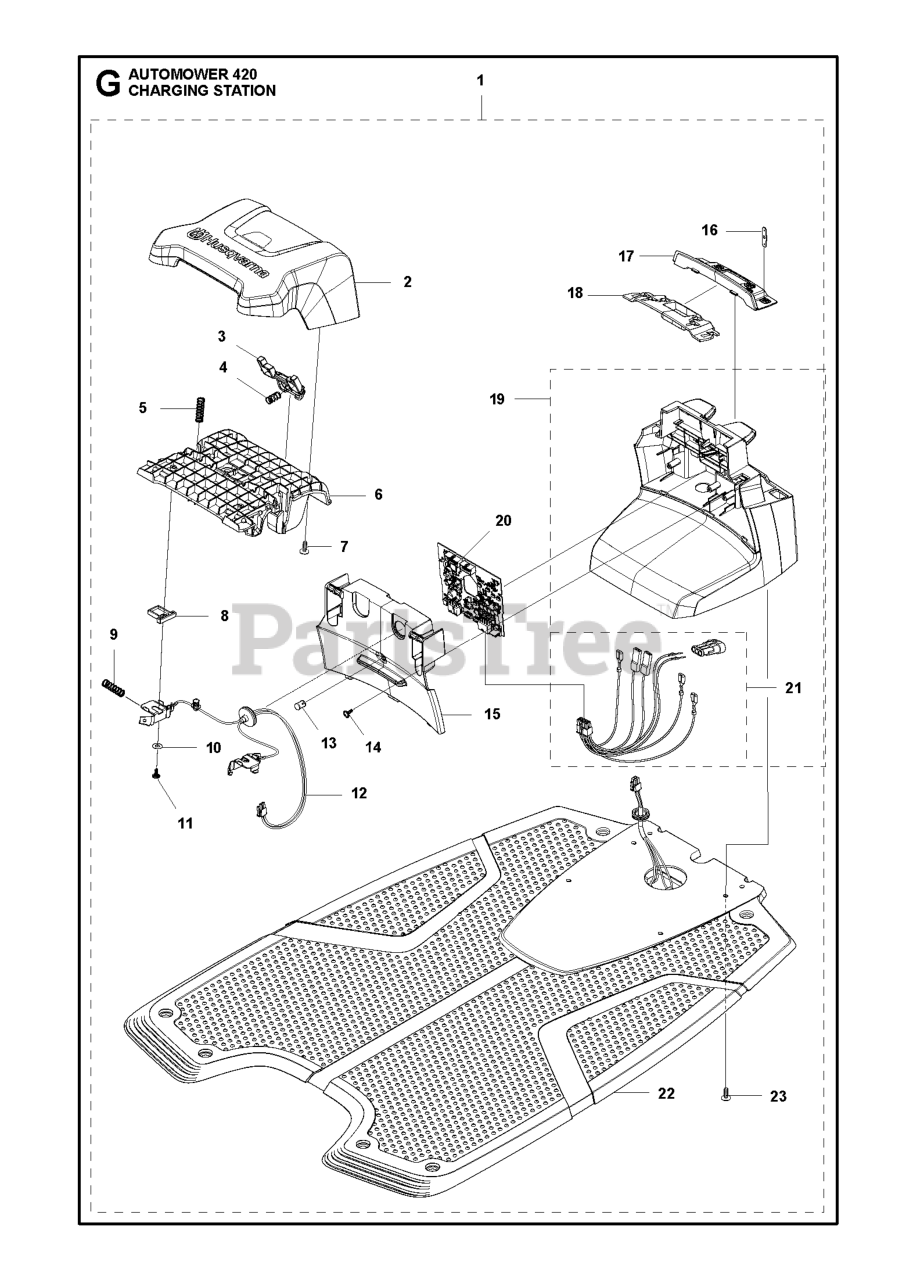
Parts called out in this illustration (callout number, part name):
2	CAP CHARGING STATION
3	BUTTON CHARGING STATION, RELEA
4	SPRING STOP BUTTON
5	SPRING SPRING CAP
6	FRAME CHARGING STATION
7	SCREW 14MM
9	SPRING SPRING CAP
10	WASHER
11	SCREW 14MM
12	CABLE ASSY CHARGING CONTACTS
13	LENS DIODE
14	SCREW 14MM
15	LID CHARGING STATION 320, ONE
16	TERMINAL TERMINAL CHARGING STA
17	PAN CHARGING STATION 320, ONE
18	HOLDER CHARGING STATION
19	HOUSING ASSY CHARGING STATION
20	PRINTED CIRCUIT ASSY PCBA CS B
20	PCBA CS BOARD
21	CABLE KIT GENERATOR BOARD
22	BASE ASSY CHARGING STATION
23	SCREW 14MM
